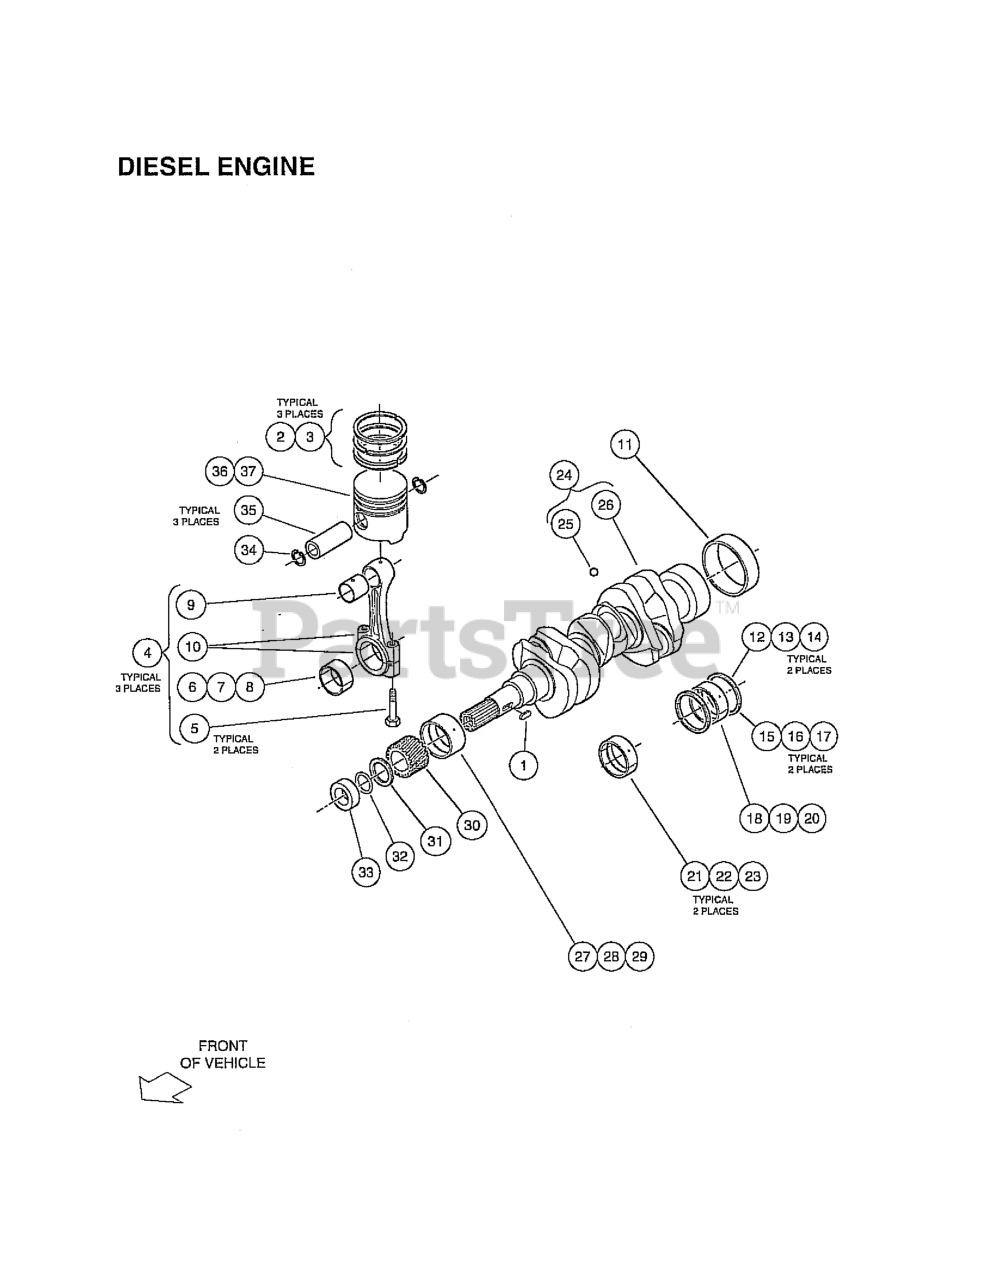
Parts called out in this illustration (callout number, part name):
1	KEY, FEATHER, SHORT CAMSHAFT
2	ASSY PISTON RING, D722 STD
3	ASSY PISTON RING, D722 + .025
4	ASSY, CONNECTING ROD
5	BOLT, CONNECTING ROD
6	METAL, CRANK, ROD, D722, STD
7	METAL, CRANK, ROD, D722, .020
8	METAL, CRANK, ROD, D722, .040
9	BUSHING, PISTON PIN, D722
11	SLEEVE, CRANKSHAFT
12	METAL, CRANK, 0 SIDE, STD
13	METAL, CRANK, 0 SIDE + .020
14	METAL, CRANK, 0 SIDE, +.040
15	METAL, CRANK, 1 SIDE, STD
16	METAL, CRANK, 1 SIDE, +.020
17	METAL, CRANK, I SIDE, +.040
18	METAL, CRANK, MAIN, REAR STD
19	METAL, CRANK, MAIN, REAR-.020
20	METAL, CRANK, MAIN, REAR-.040
21	METAL, CRANK, MAIN, MID STD
22	METAL, CRANK, MAIN, MID+.020
23	METAL, CRANK, MAIN, MID+.040
24	COMP, CRANKSHAFT
25	BALL, CRANKSHAFT
27	METAL, CRANK, D722, FRNT, STD
28	METAL, CRANK, 722, FRNT, -.020
29	METAL, CRANK, 722, FRNT, -.040
30	GEAR, CRANK
31	SLINGER, OIL
32	O RING, 23X26
33	COLLAR, CRANKSHAFT
34	CIRCLIP, PISTON PIN
35	PIN, PISTON
36	PISTON, D722, STD
37	PISTON, D722, +0.25
